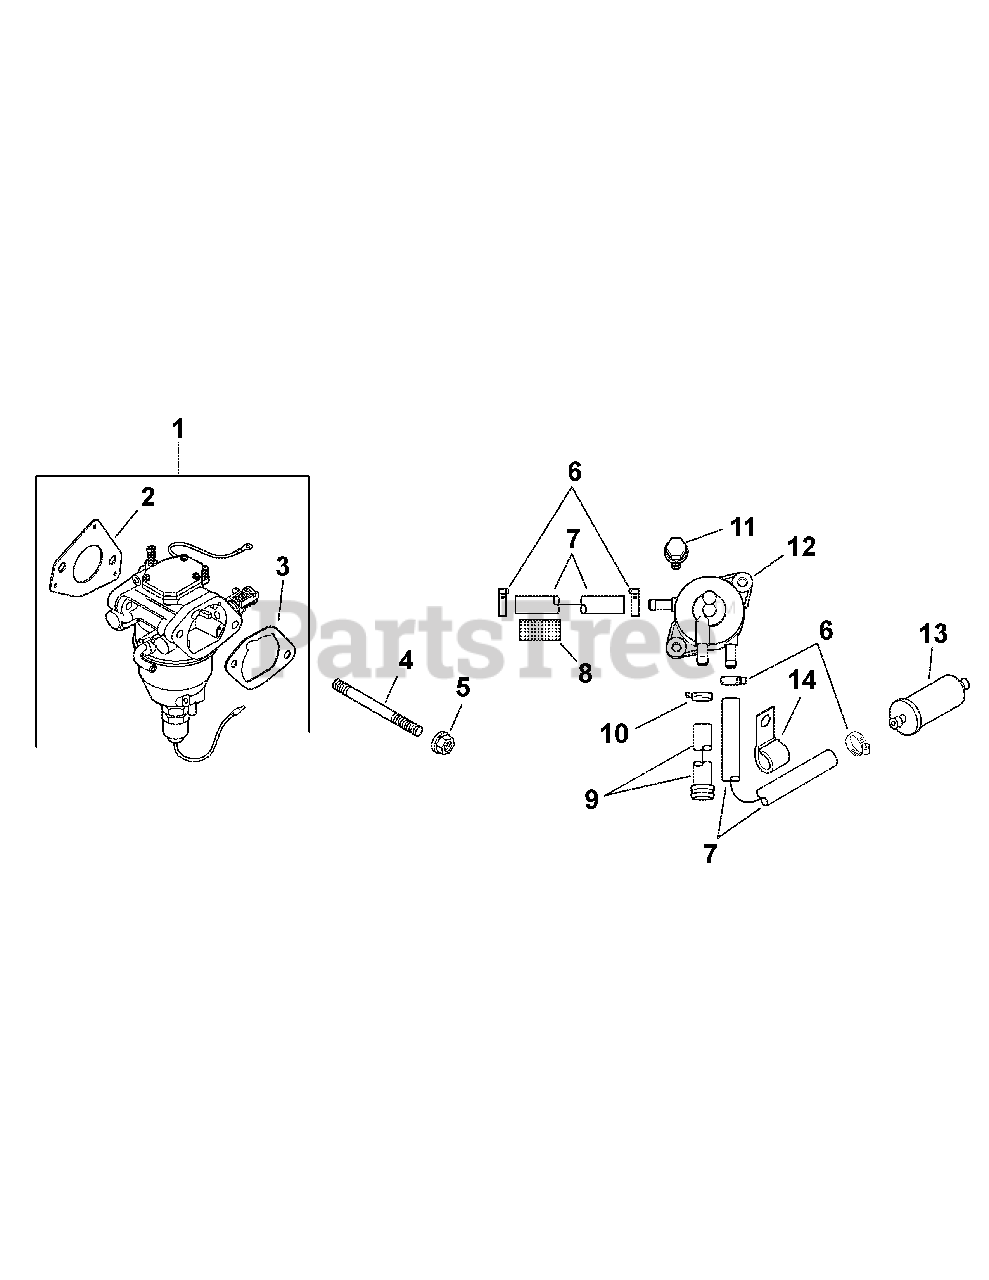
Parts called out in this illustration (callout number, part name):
1	Kit, Carburetor
2	Gasket, Carburetor
3	Gasket, Air Cleaner Base
4	Stud, M6 x 1.0 x 106
5	Nut, Flange, M6 x 1.0
6	Clamp, Spring Hose 1/2
7	Line, Fuel
8	Sleeve, Anti Abrasion
9	Kit, Fuel Pump Hose w/Clamp
11	Screw, Tap, M6 x 1.7 x 18
13	Filter, Fuel
